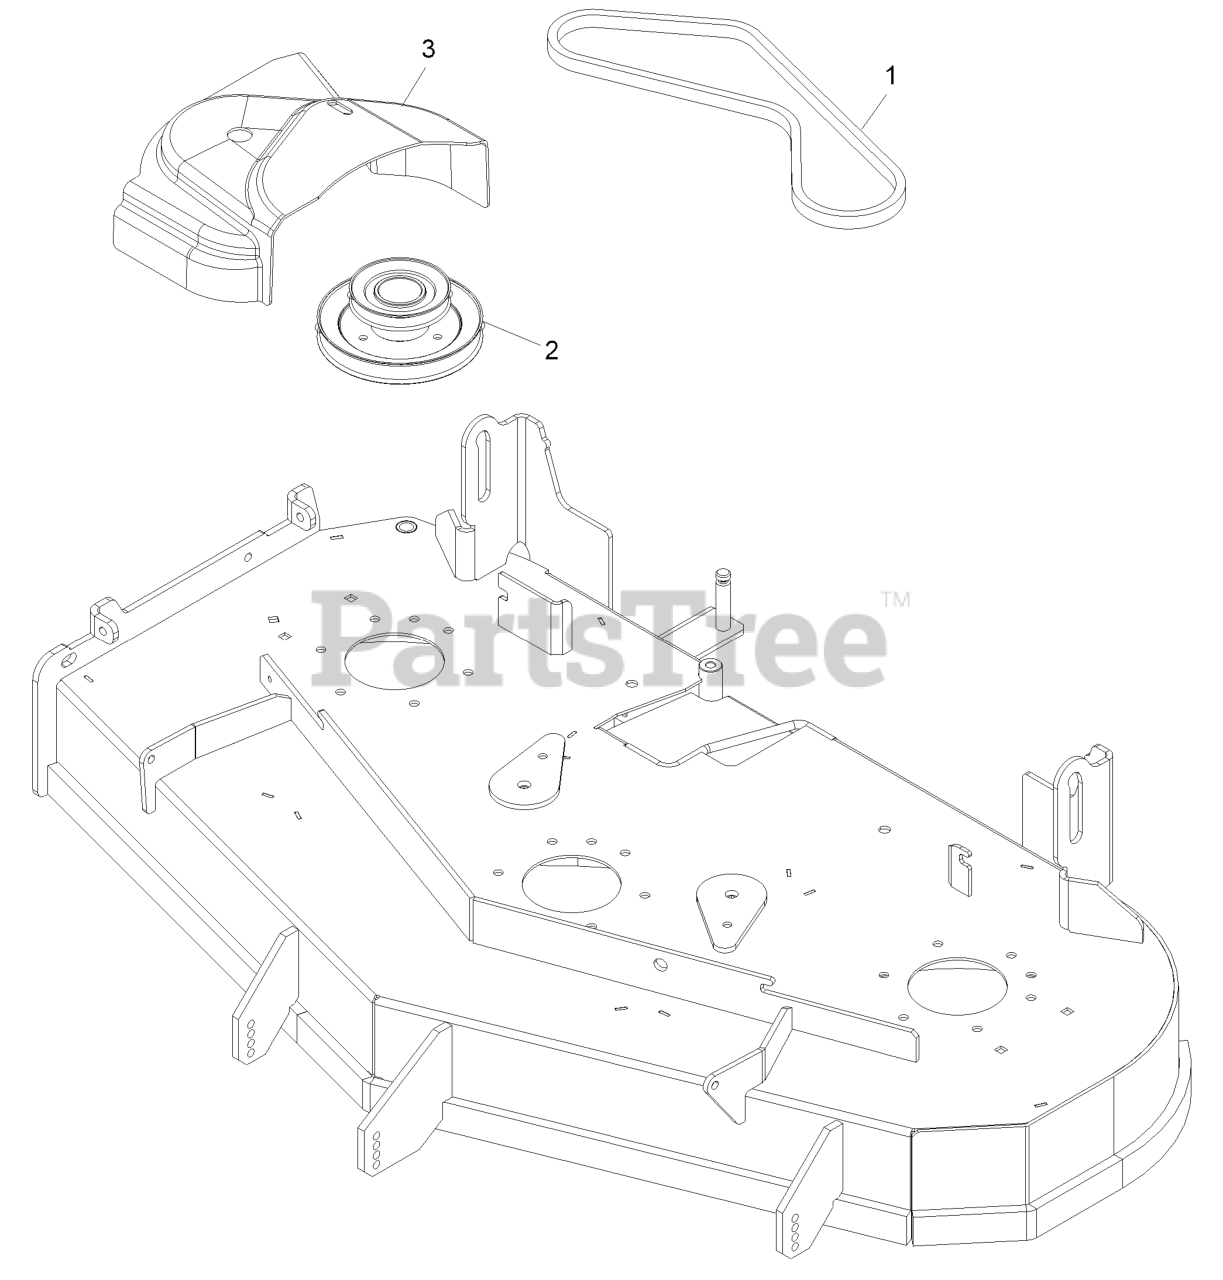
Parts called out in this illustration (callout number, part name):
1	BELT, BLOWER 52"DECK
2	JACKSHAFT,UV DRIVE 524 SP
3	COVER,BELT UV 52
